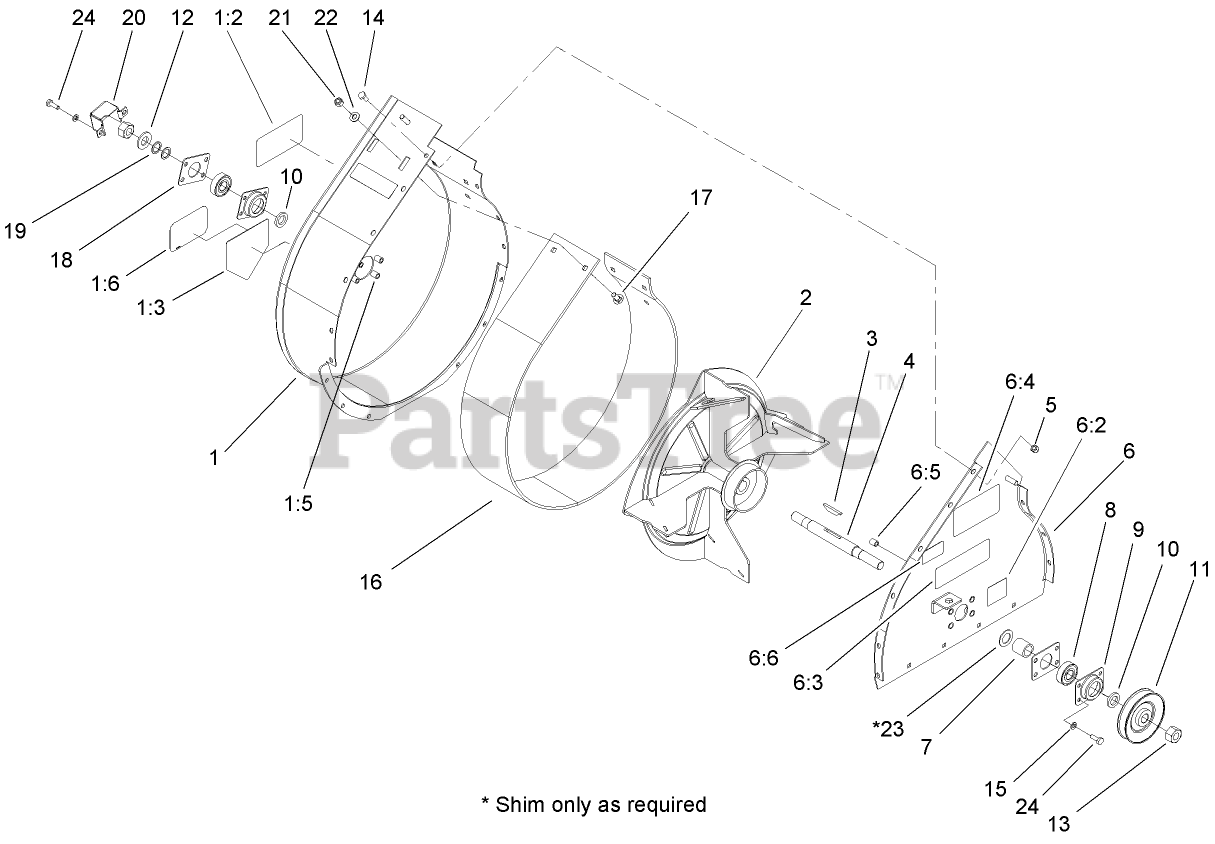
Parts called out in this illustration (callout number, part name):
1	BLOWER HOUSING ASM
1:2	DECAL-DANGER
1:3	DECAL-DANGER
1:5	INSERT-NUT
1:6	DECAL
2	IMPELLER ASM
4	Shaft-Blower
5	NUT-LOCK, NI
6	COVER PLATE ASM
6:2	DECAL-WARNING
6:3	DECAL-DANGER
6:4	DECAL-DANGER
6:5	INSERT-NUT
6:6	DECAL-PROTECTION, EAR
7	Spacer
8	BEARING-BALL
9	CUP-BEARING
10	SPACER-BEARING
11	Pulley ASM
12	WASHER-FLAT
13	NUT-HEX
14	SCREW-HH
15	WASHER-LOCK
16	STRIP-WEAR
17	BOLT-CARR
18	PLATE-COVER
19	WASHER-FLAT
20	Cover-Shaft
21	NUT-LOCK, NI
22	WASHER-PLAIN
23	WASHER-THRUST
24	SCREW-HH
